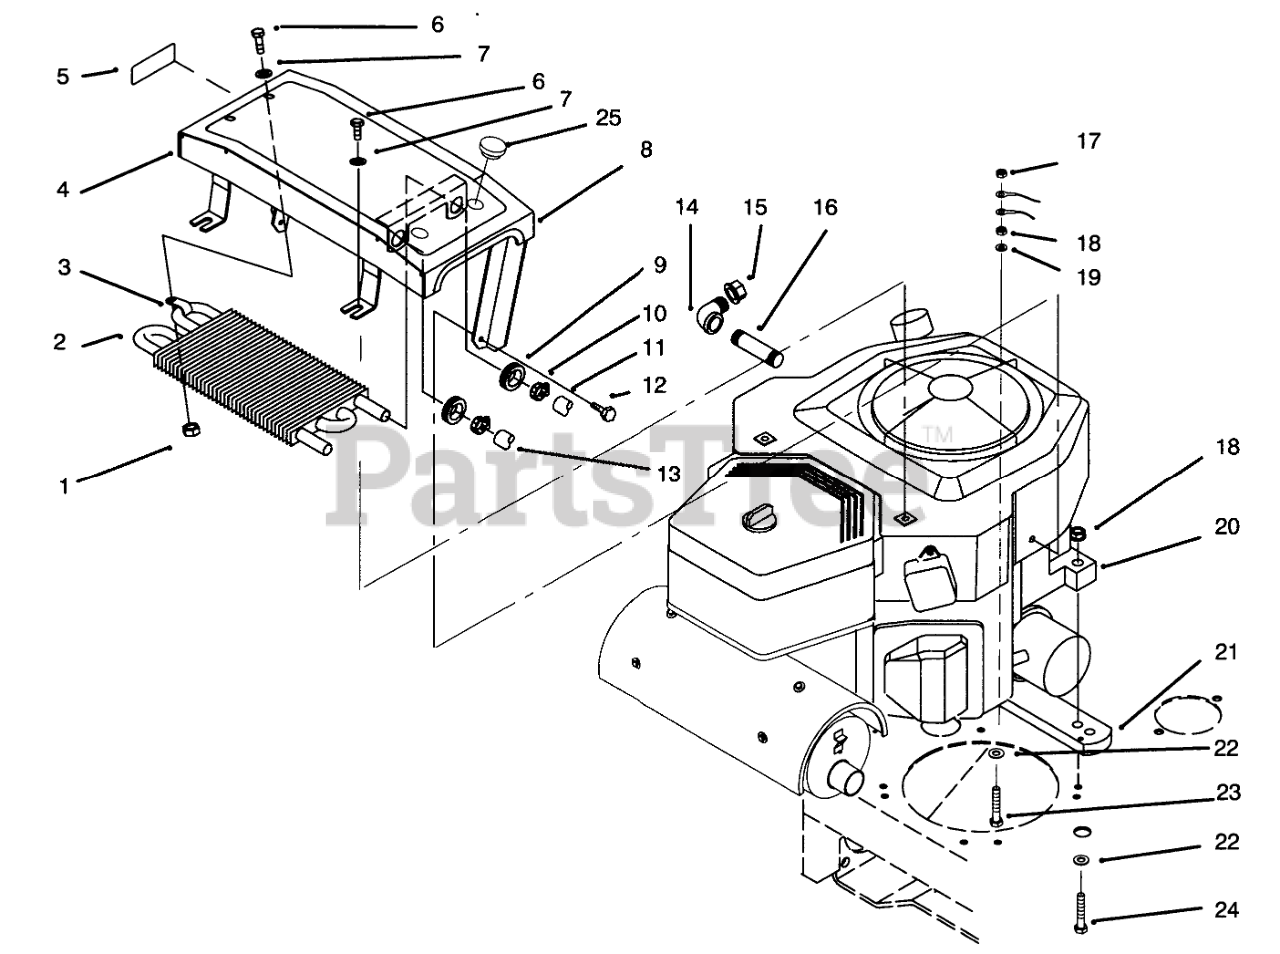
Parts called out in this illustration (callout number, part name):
1	NUT-LOCK, NI
2	Cooler-Oil
3	CLAMP-R
4	Mount-Cooler
5	DECAL-FUEL SHUT OFF
6	SCREW-HH
7	WASHER-FLAT
8	TRIM-MOUNT, COOLER
9	GROMMET
10	CLAMP-HOSE
11	HYDRAULIC HOSE ASM
12	Screw-w/Engine
13	HYDRAULIC HOSE ASM
14	ELBOW-STREET, 90 DEG
15	CAP-PIPE
16	NIPPLE
17	NUT-KEPS
18	NUT-HEX, SIDE DEFORM
19	WASHER-LOCK
20	Engine 18Hp. Kohler (Ref.)
21	SPACER - ENGINE
22	WASHER-PLAIN
23	SCREW-HH
24	SCREW-HH
25	PLUG-PLASTIC
